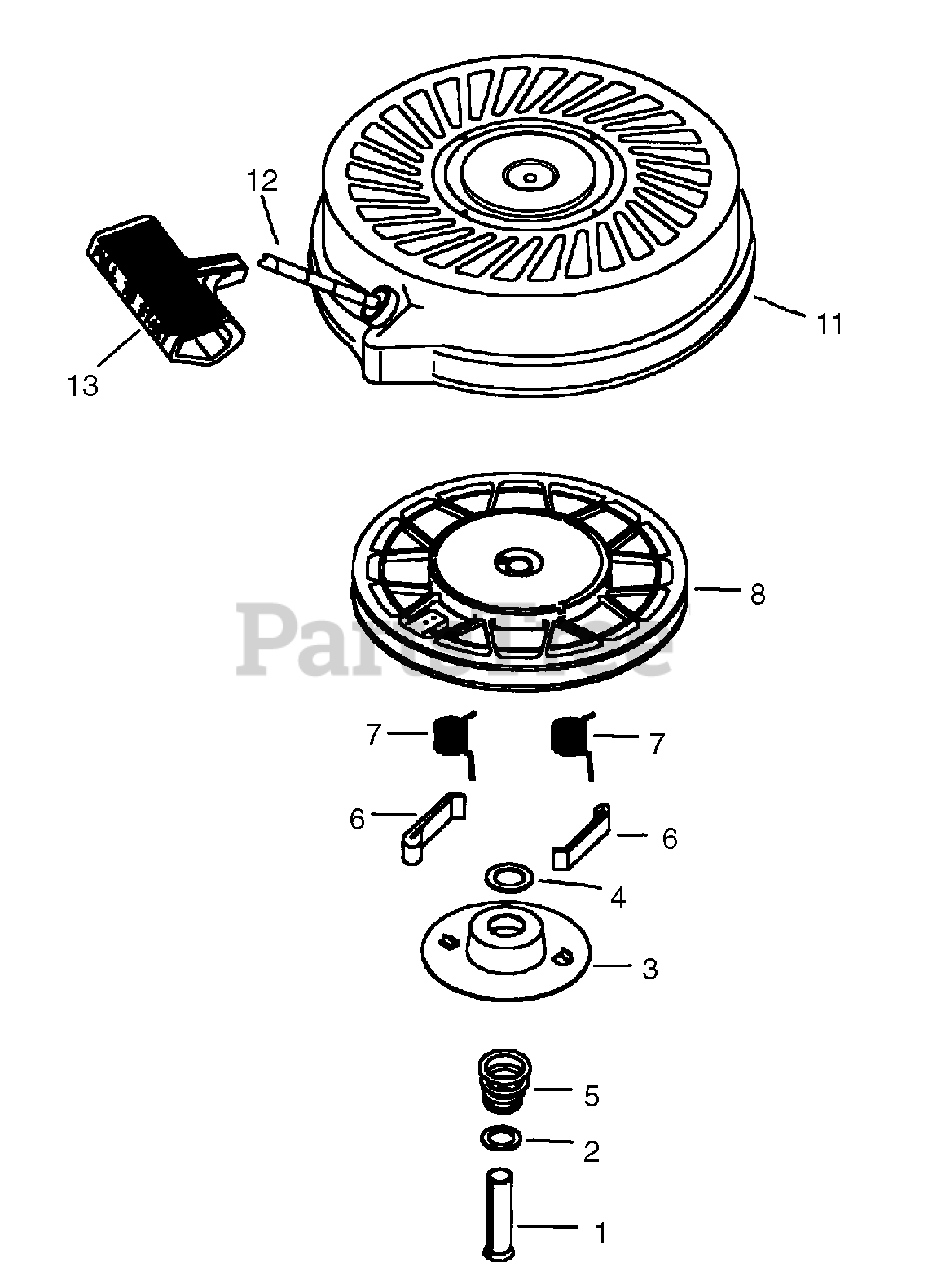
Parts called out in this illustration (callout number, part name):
1	Spring Pin (Incl. 4)
2	Washer
3	Retainer
4	Washer
5	Brake Spring
6	Starter Dog
7	Dog Spring
8	Pulley & Rewind Spring ASM
11	Starter Housing ASM (40 degree grommet)
12	Starter Rope ( 98" X 9/64" dia.)
13	Starter Handle
